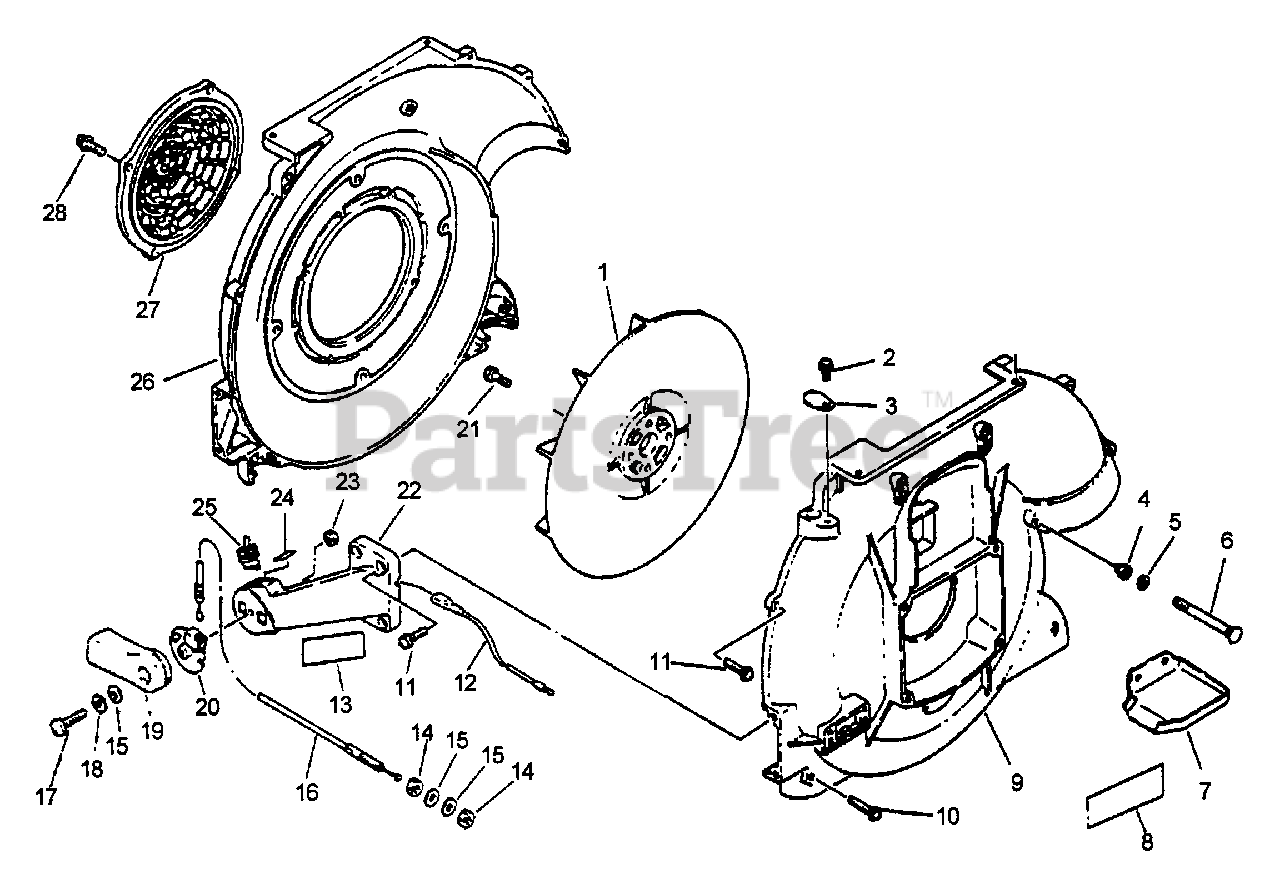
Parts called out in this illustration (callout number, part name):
2	SCREW - 5X10
4	NUT - 5 -- CAP
5	WASHER - 5
6	BOLT, ELBOW
7	BRACKET, MUFFLER COVER
8	LABEL - NOISE
9	COVER, FAN - OUTER
10	SCREW - 5X25
11	SCREW - 5X20
13	LABEL - CAUTION
15	WASHER - 6
16	CABLE, THROTTLE
17	SCREW - 6X25
18	LOCKWASHER - 6
19	TRIGGER, THROTTLE
21	BOLT - 5X16
22	MOUNT, THROTTLE LEVER
23	LOCKNUT - 6
24	LABEL - STOP
25	IGNITION SWITCH ASSY
26	COVER, FAN - INNER -- ORANGE
27	GUARD, DEBRIS
28	BOLT - 6X14
